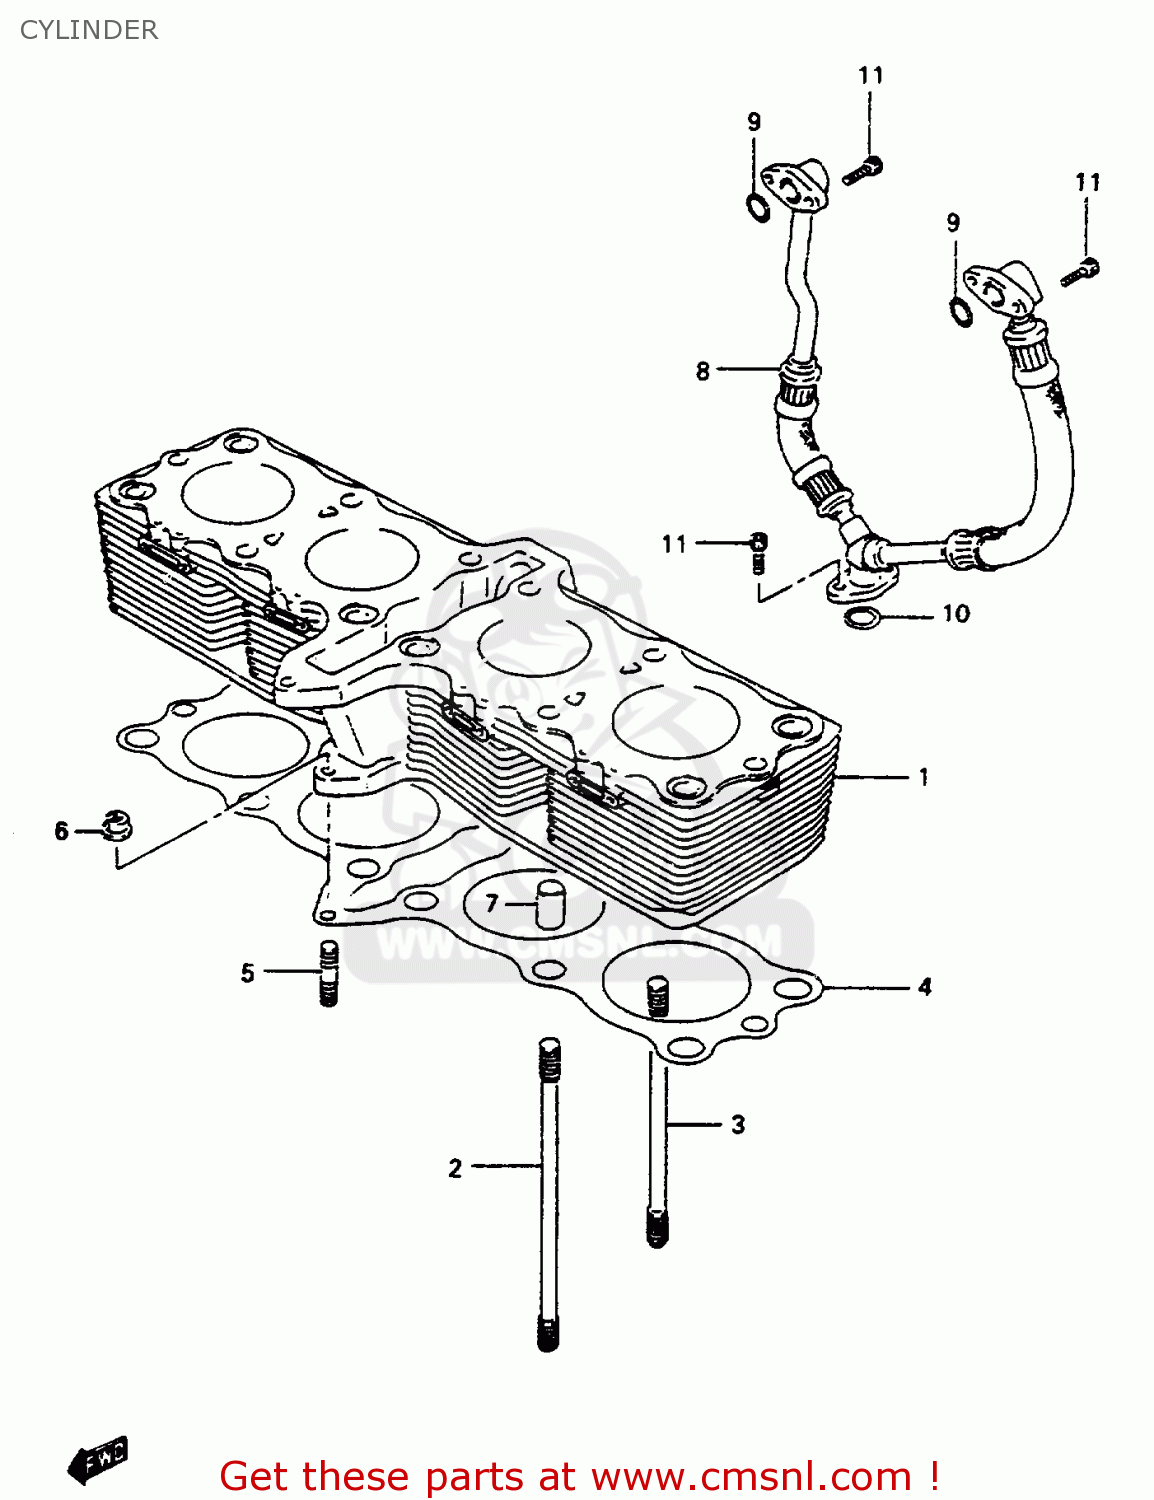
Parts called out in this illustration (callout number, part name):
1	CYLINDER COMP
2	STUD BOLT (L:150)
3	BOLT,STUD
4	GASKET,CYLINDER (NAS)
5	STUD,M6X1X32
6	NUT
7	PIN(13X10.4X20)
8	HOSE,OIL HEAD COOLER
9	O RING(D:2.5,ID:13.8)
10	O RING(D:2.4,ID:15.8)
11	BOLT,OIL FILLE
